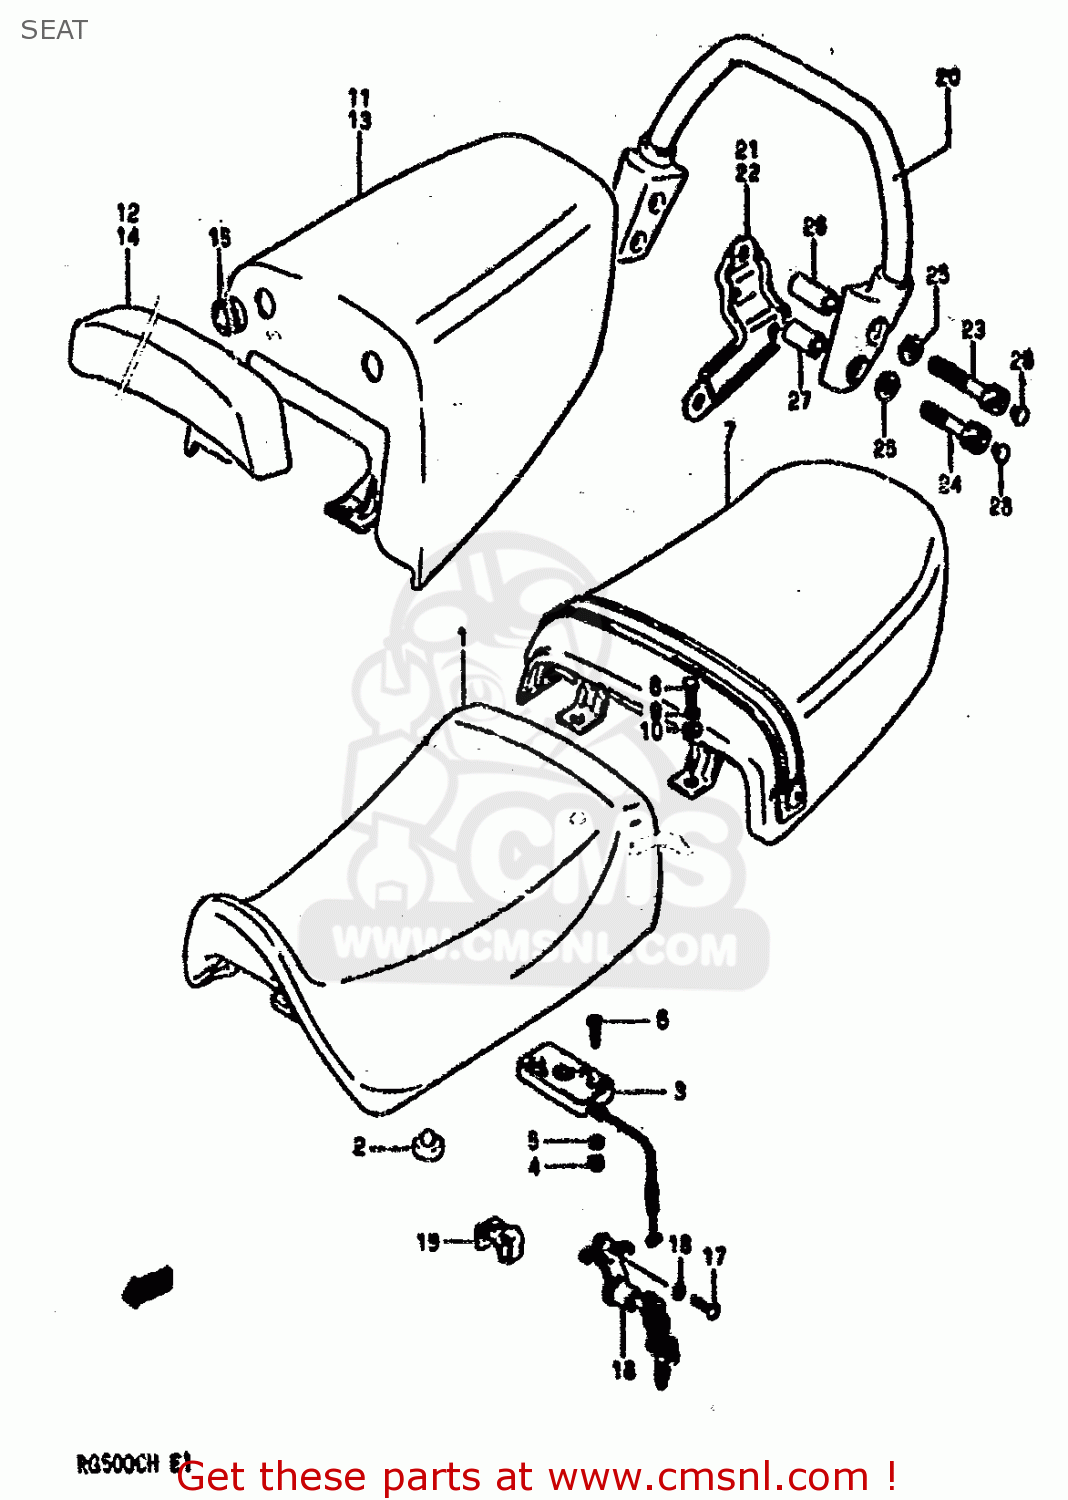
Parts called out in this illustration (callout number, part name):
1	SEAT ASSY (BLUE)
2	CUSHION
3	BRACKET,SEAT SUPPORT REAR
4	NUT
5	WASHER,LOCK
6	SCREW
7	SEAT ASSY,PILLION (BLUE)
8	BOLT
9	WASHER,LOCK
10	WASHER(6.5X16X1.2)
11	BOX SET,SEAT T
12	BACKREST,SEAT
13	BOX SET,SEAT TAIL (RED)
14	BACKREST,SEAT (RED)
15	CUSHION
16	LOCK ASSY,SEAT
17	SCREW
18	WASHER,LOCK
19	HOLDER,HELMET
20	HANDLE,PILLION RIDER
21	PLATE,PILLION HANDLE RH
22	PLATE,PILLION HANDLE LH
23	BOLT
24	BOLT 8X45
25	WASHER
26	SPACER (8.6X13.8X35)
27	SPACER (8.6X13.8X28)
28	CAP(OD:10)
